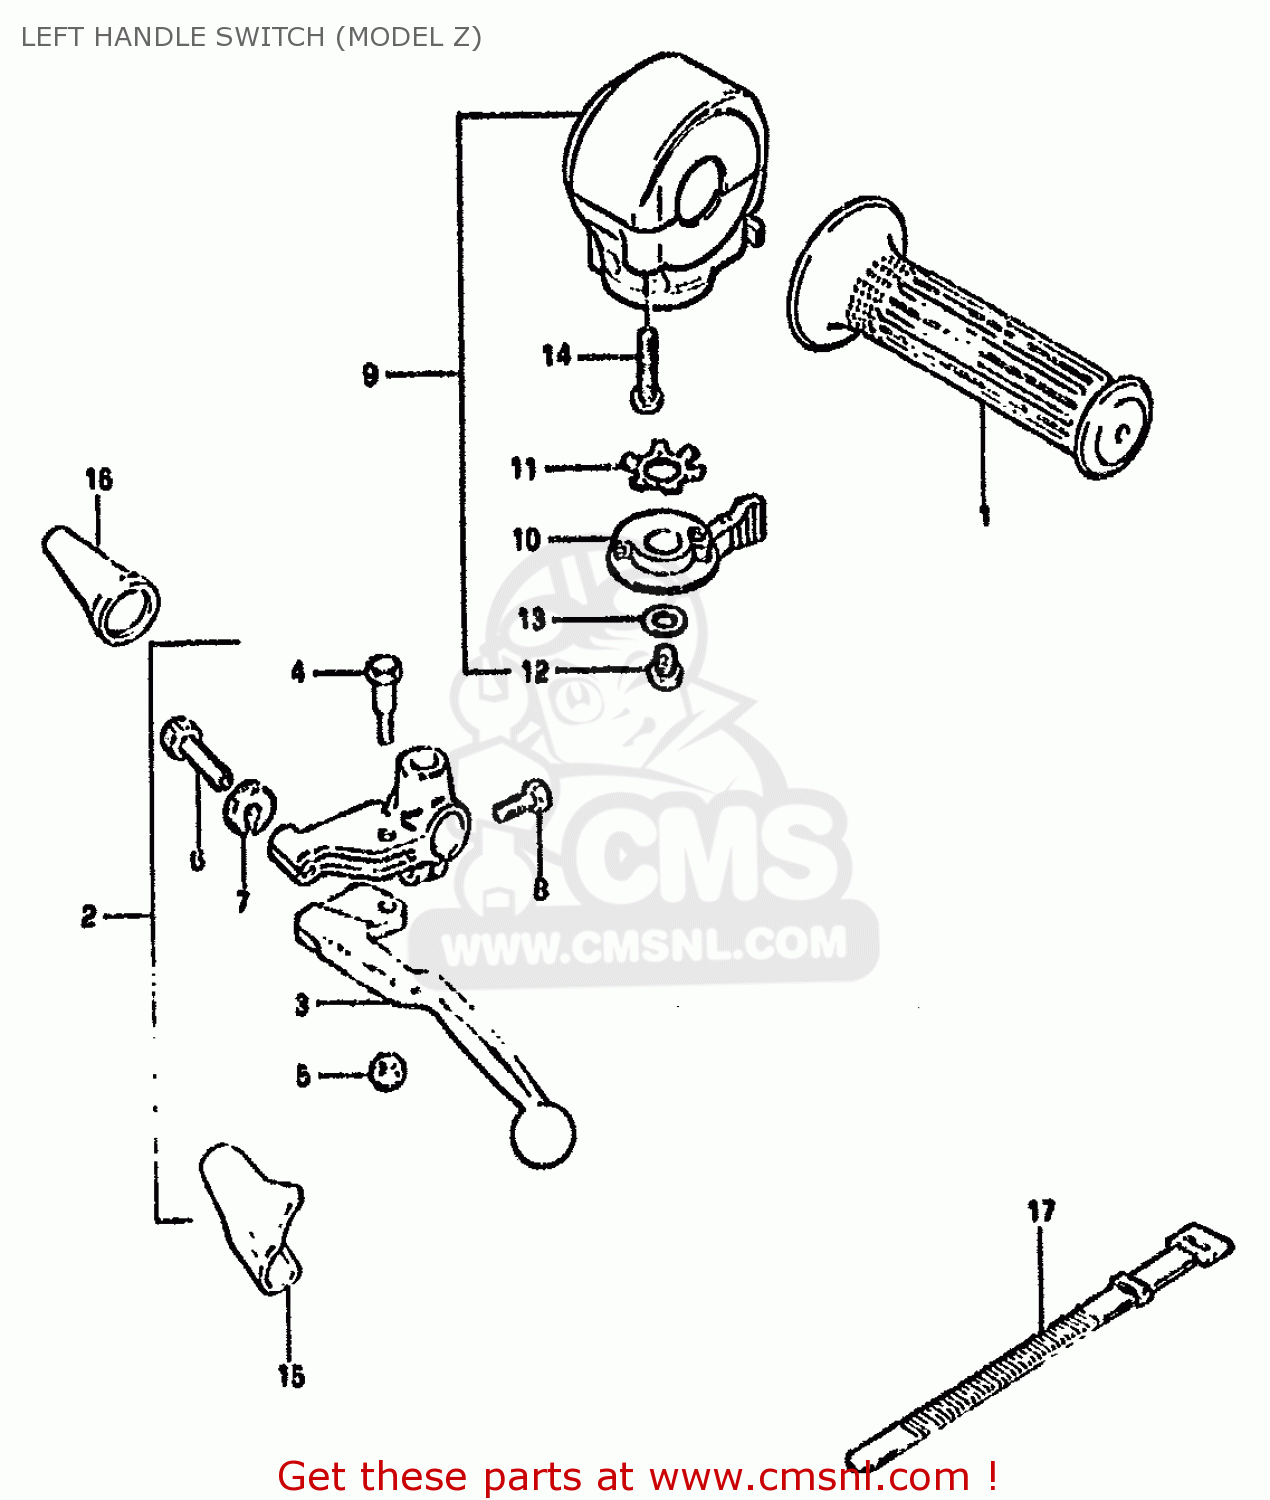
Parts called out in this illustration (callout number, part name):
1	GRIP,L
2	LEVER ASSEMBLY
3	LEVER,CLUTCH
4	BOLT,LEVER
5	NUT 6MM
6	ADJUSTER,CABLE
7	NUT,CABLE ADJUSTER
8	BOLT
9	SWITCH ASSY, HANDLE LH
10	LEVER,STARTER
11	WASHER
12	SCREW
13	WASHER 6MM
14	SCREW
15	COVER,CLUTCH LEVER
16	BOOT,CLUTCH CABLE
17	CLAMP(L:120)
